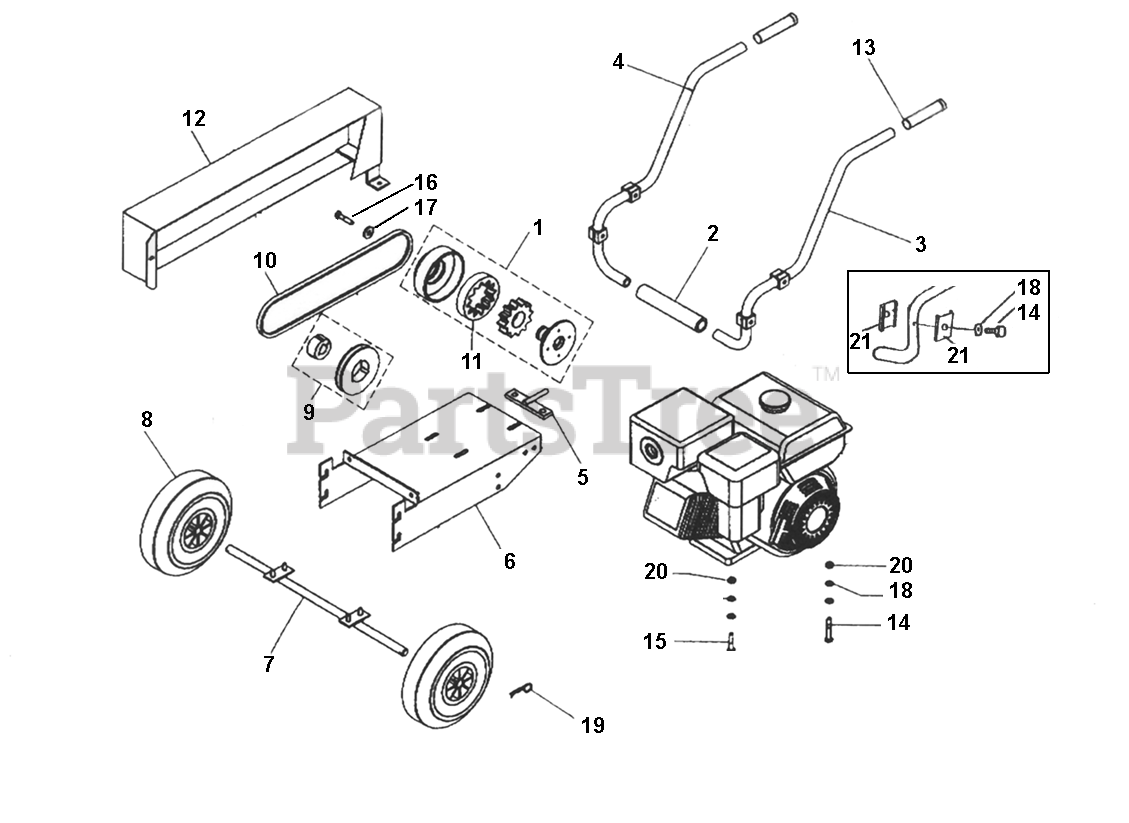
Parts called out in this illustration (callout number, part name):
1	CLUTCH COMPLETE
2	RUBBER HOSE
3	HANDLEBARLH
4	HANDLEBARRH
5	BELT TENSIONER
6	DECK, ENGINE SUPPORT B&S
7	AXLE, WHEEL
9	PULLEY W TAPER LOCK
11	CLUTCH RUBBER, STAR
12	BELT SHIELD B&S
13	HANDLE GRIP
14	BOLT M8X60 B&S
15	BOLT M8X40, B&S
16	BOLT 3/8 X 1.5" UNF, B&S
